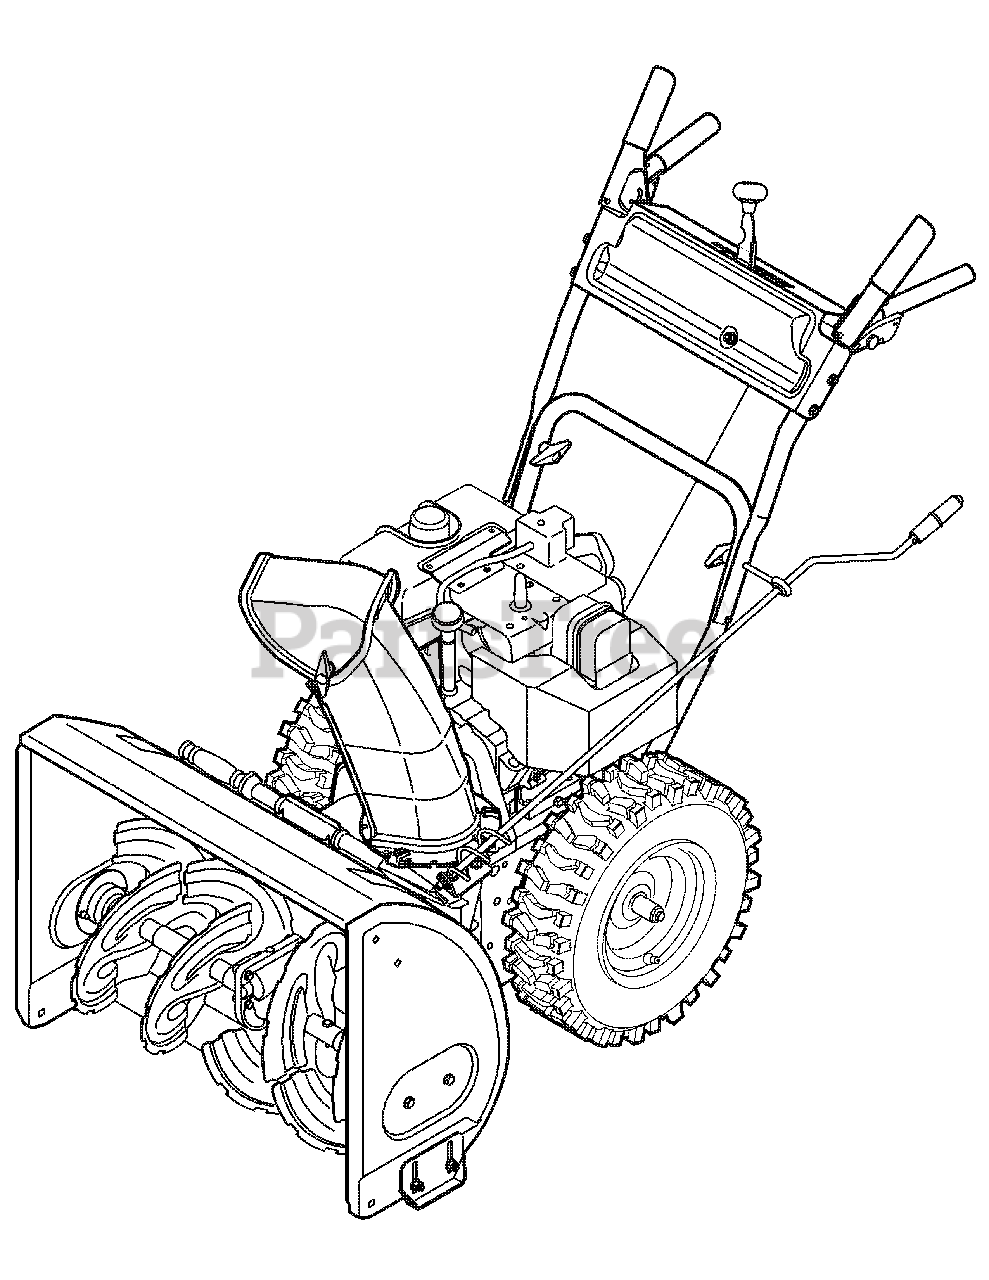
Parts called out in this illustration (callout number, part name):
NA	Lamp
NA	Spiral Crescent
NA	Rubber Paddle
